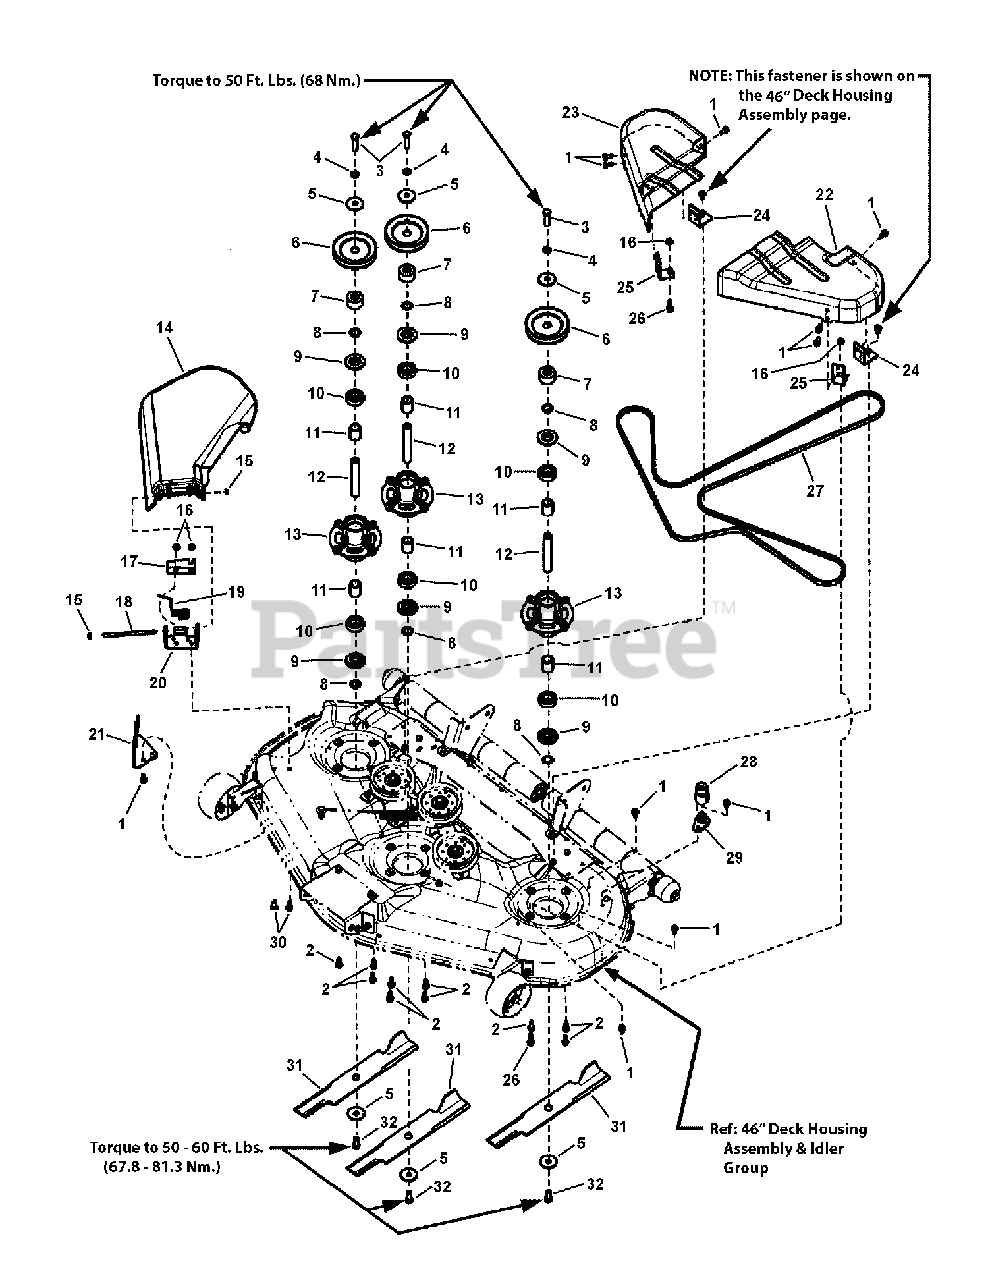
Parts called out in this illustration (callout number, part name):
1	SCREW, 5/16-18 x 3/4" Hex Washer Head Self-Tap, Black
2	SCREW, 5/16-18 x 1" Hex Washer Head Self-Tap, Black
3	SCREW, 7/16-14 x 1-3/4" Hex Head Cap, GR 5, Black
4	LOCKWASHER, .438, Spring, Black
5	WASHER, .475 ID x 1.75 OD x .156 Thick Spring, Black
6	PULLEY, 4.6 OD 11 Ga Split 46" Mower
7	SPACER, Pulley P'Metal 46" Mower ZTR
8	RING, Self-Locking, 46" Mower
9	SHIELD, Arbor, 2.050 OD
10	BALL BEARING, 20 MM
11	SPACER, Bearing Powdered Metal
12	SHAFT, Spindle 20MM Dia. 134.60 MM Long
13	HOUSING, Spindle, Cast Steel, Machine
14	DEFLECTOR, Discharge, Plastic 46/52 Decks
15	PUSH NUT, 5/16"
16	NUT, 5/16-18 Hex Flange Lock, Small - Black
17	PLATE, Deflector Closeoff
18	ROD, Hinge, .313 Dia. 5.6 Long Zinc Plated, 46" Mower
19	SPRING, Torsion Deflector, 2.16 Long, 46" Mower
20	PIVOT, Hinge
21	BAFFLE, Pinchoff
22	COVER, Spindle, 46/52 Deck, LH 285Z
23	COVER, Spindle, 46/52 Deck, RH 285Z
24	BRACKET, Rear Deck Cover Support 285Z
25	BRACKET, 46"/52" Cover Mounting
26	SCREW, 5/16-18 x 1-1/4" Hex Washer Face Self-Tap
27	BELT, 143.35 Effective Length, A-Wedge, 46" RZT
28	CONNECTOR, Washout Port 46/52" Black Poly
29	ADAPTER, Washout Port 46/52" Mowers
30	BOLT, 5/16-18 x 7/8" Round Head Short Square Neck, GR 5, Black
31	BLADE, Mower, 18.50 Long, 52" Deck
32	SCREW, 7/16-14 x 1" Hex Head Cap, GR 5, Black
